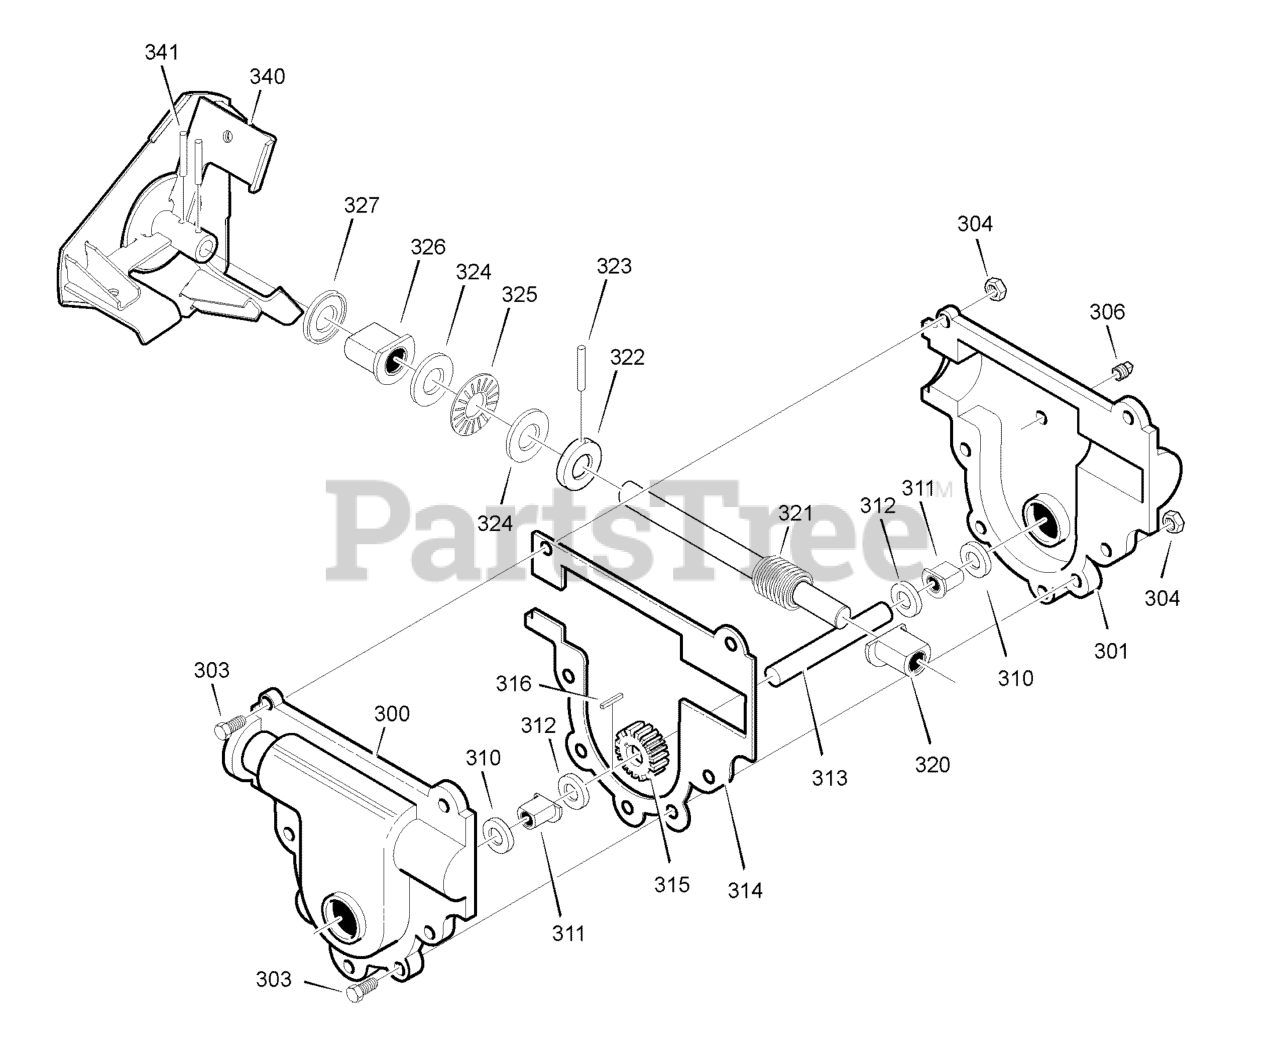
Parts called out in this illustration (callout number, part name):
300	CASE, Gear, Right
301	CASE, Gear, Left
303	SCREW, 1/4-20 x 3/4
304	NUT, 1/4-20
306	SCREW, 3/8-16 x 1/2
310	SEAL, Oil
311	BEARING, Flange
312	WASHER, Flat
313	SHAFT, Auger Output
314	GASKET, Gearbox
315	GEAR, Worm
316	KEY, Woodruff
320	BEARING, Flange
321	SHAFT, Auger Input (Impeller)
322	COLLAR, Thrust
323	PIN, Spring
324	WASHER, Flat
325	BEARING, Roll
326	BEARING, Flange
327	SEAL, Oil
340	IMPELLER
341	PIN, Spring
